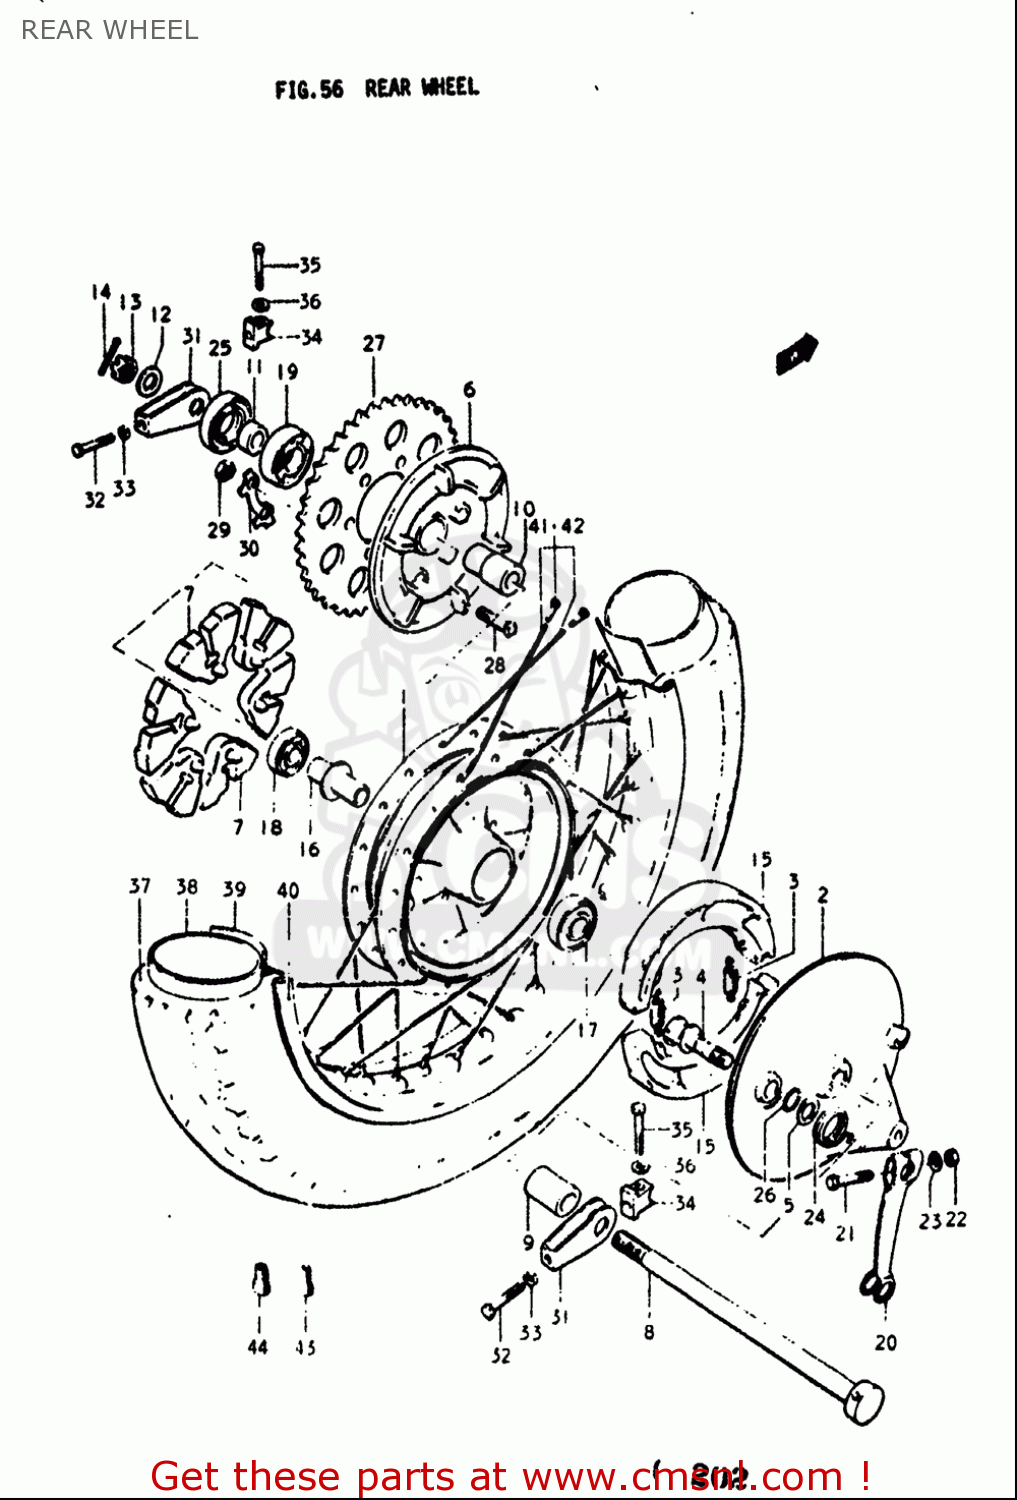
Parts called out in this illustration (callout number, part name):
3	SPRING,BRAKE SHOE
5	WASHER(15.5X24X1.6)
7	ABSORBER,RR HUB SHOCK
8	AXLE,REAR
10	SPACER,REAR HUB BEARING
12	WASHER
13	NUT
14	PIN, COTTER
15	SHOE SET,BRAKE (NAS)
16	SPACER
17	BEARING
18	BEARING
19	BEARING(25X52X15)
21	BOLT
22	NUT
23	WASHER
24	SPRING
25	SEAL,OIL(30.5X52X8)
26	O RING(D:2.4,ID:14.8)
27	SPROCKET,REAR (NT:44)
28	BOLT(10X35.5)
29	NUT
30	WASHER
31	ADJUSTER,CHAIN
32	BOLT(8X50)
33	NUT
34	SUPPORTER,CHAIN ADJUST
35	BOLT
36	WASHER
38	TUBE ASSY,INNER
39	PROTECTOR,INNER TUBE
40	RIM,RR WHEEL
41	SPOKE SET,RR WHEEL
43	BALANCER,WHEEL (B)
44	BALANCER,WHEEL (30G)
